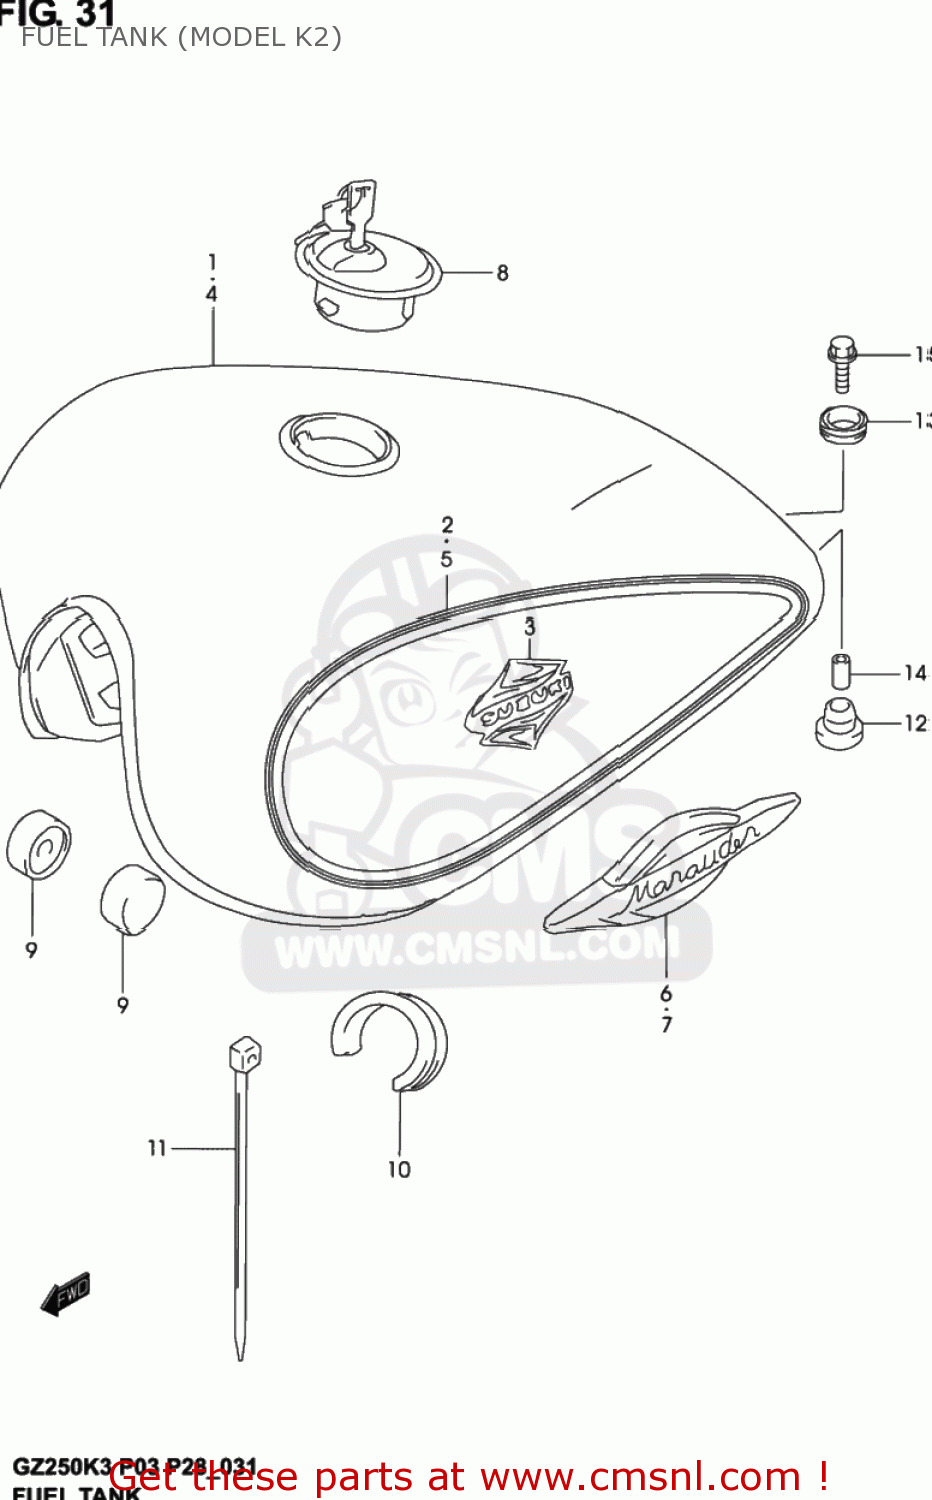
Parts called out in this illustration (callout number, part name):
1	TANK ASSY,FUEL(RED)
2	TAPE SET,FUEL TANK
3	EMBLEM,FUEL TANK
4	TANK ASSY,FUEL(BLACK)
5	TAPE SET,FUEL TANK
6	TANK EMBLEEM
7	EMBLEEM, TANK
8	CAP SET,FUEL TANK
9	CUSHION
10	CUSHION,FUEL TANK SIDE
11	CLAMP
12	CUSHION
13	CUSHION,FUEL TANK RR
14	SPACER(6.5X9X18)
15	BOLT
